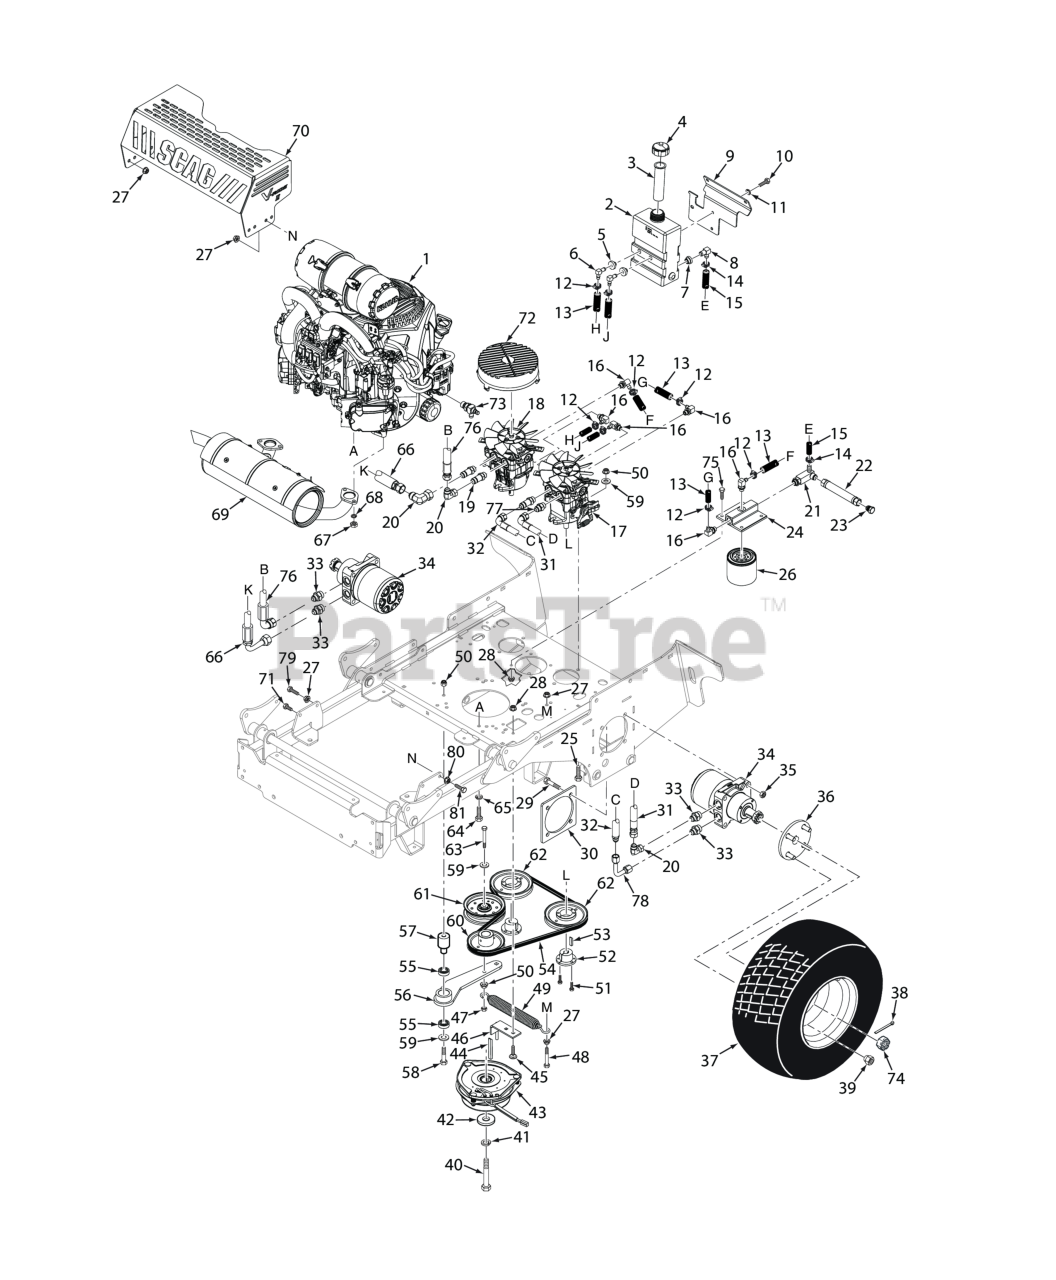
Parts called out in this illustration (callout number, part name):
1	Engine, Kawasaki 31FX (FX921)
2	Engine, Kohler - 23CV
3	Insert, Filler Neck
4	CAP, HYDRAULIC TANK
5	Bushing, 0.56" Dia. Viton
6	Elbow, 90 Degree, 9/16-18 JIC x 9/16 O-Ring
7	Bushing, 0.78" Dia. Viton
8	Fitting, 90 Degree - 1/2" Hose
9	Bracket, Hydro Tank Mounting
10	BOLT, SERRATED FLANGE HEX HEAD 5/16-18 X 3/4"
11	Lockwasher, 5/16 (.317 x .586 x .078) Helical Spring
12	Clamp, .69" Max. / .25" Min. Dia.
13	Hose, 3/8" ID - 10-1/4" Long (Order By The Inch)
14	Clamp, Cable 3/4" I.D.
15	Hose Assembly, 1/2" ID (Oil Reservoir to Filter Base)
16	Elbow, 90 Degree - 9/16" O-Ring x 3/8" Hose
17	Pump, LH - SVRII
18	Pump, RH - SVRII
19	Union, O-Ring to JIC
20	Elbow, 1/2 JIC Female to 1/2 JIC Male
21	Tee, 3/4" O-Ring
22	Drain, Hose Assembly
23	Plug, JIC 3/4-16 UNF
24	Filter Head Assembly
25	Bolt, Hex Head 3/8-16 x 1-1/2" B&S 32BV
26	OIL FILTER, SPECIAL
27	NUT, 3/8-16 SERRATED FLANGE HEX HEAD
28	Nut, Serrated Flange 5/16-18 (Right Front Engine Mounting, Briggs and Kohler Only)
29	Bolt, Hex Hd. 1/2-13 x 2-1/2" (lower)
30	Plate Weldment, Motor Backing
31	Hose Assembly
32	Hose Assy., 18-1/2"
33	TUBE UNION, 3/4-16 JIC TO 7/8-14 "O" RING
34	Wheel Motor, Parker
35	Locknut, Hex 1/2-13 Center Lock
36	Wheel Hub Assy., SVRII
37	Wheel Assembly, 24 x 12-12 (SPZ61)
38	Pin, Cotter 9/16" x 1-1/2"
39	Wheel Nut, 1/2-20 x 13/16
40	Bolt, Hex Head 7/16-20 x 2-1/4" w/Patch (Kawasaki)
41	Lockwasher, 7/16� Spring
42	Flatwasher, 7/16-.469 x 1.75 x .25 (48, 52)
43	Clutch w/Tag GT2.5-FE02 (48 / 52)
44	Key, 1/4 x 1/4 x 3-1/2"
45	Bolt, 5/16-18 x .75 RHSN Carriage
46	ANTI-ROTATION WLMT, SVRII
47	Bolt, Hex Head 3/8-16 x 1" Ser. Flg.
48	Bolt, Hex Head 3/8-16 x 3" - 52"
49	Spring, Transmission Idler
50	HEX NUT, ELASTIC STOP LOCK, 3/8-16
51	Bolt, Hex Head 1/4-20 x 1" Grade 8 Black
52	Hub, Tapered, 15mm Bore
53	KEY, 5 MM X 5 MM X 25 MM
54	Belt, Pump Drive (48 & 52)
55	BEARINGS, BALL, NEUTRAL RETURN
56	Idler Arm Assy.
57	Pivot, Idler
58	Capscrew, Hex Head 3/8-16 x 3.25"
59	Flatwasher, 3/8 (.391 x .938 x .105 HD) Grade 8
60	Pulley, 4-3/4" OD - 1.125 Bore
61	Pulley, Idler 4-1/2"
62	Pulley, 5.45 OD - Tapered Bore"
63	Bolt, Hex Head 3/8-16 x 2-3/4" Full Thread
64	Bolt, Hex Head 5/16-18 x 1-1/2" (Right Front Engine Mounting, Briggs and Kohler Only)
65	Lockwasher, 3/8" Spring, Kawasaki FX / FT & FT-EFI / B&S 32BV
66	Hose Assy., 15-1/4"
67	Nut, M8 x 1.25 Hex Special
68	Lockwasher, M8 Spring (Kawasaki)
69	Muffler, Kawasaki FX801 - SVRII
70	Heatshield, Muffler- SVRII
71	Bolt, Hex Head, 3/8-16 x 3/4"
72	Fan Cover, Pump
73	Oil Drain, M20 Thread (Kawasaki)
74	Nut, Hex Castle 1.0-20 UNEF
75	Bolt, Heax Head 5/16-18 x 1" (48V / 52V)
76	Hose Assy., 27-1/2"
77	Union, 3/4"-16 JIC x 3/4"-16 O-Ring
78	Tube Assy.
79	Bolt, Hex Head 3/8-16 x 1-1/2" Grade 8 Black
80	NUT, 3/8-16 SERRATED FLANGE HEX HEAD
81	Bolt, Hex Head 3/8-16 x 1-1/2" Grade 8 Black
